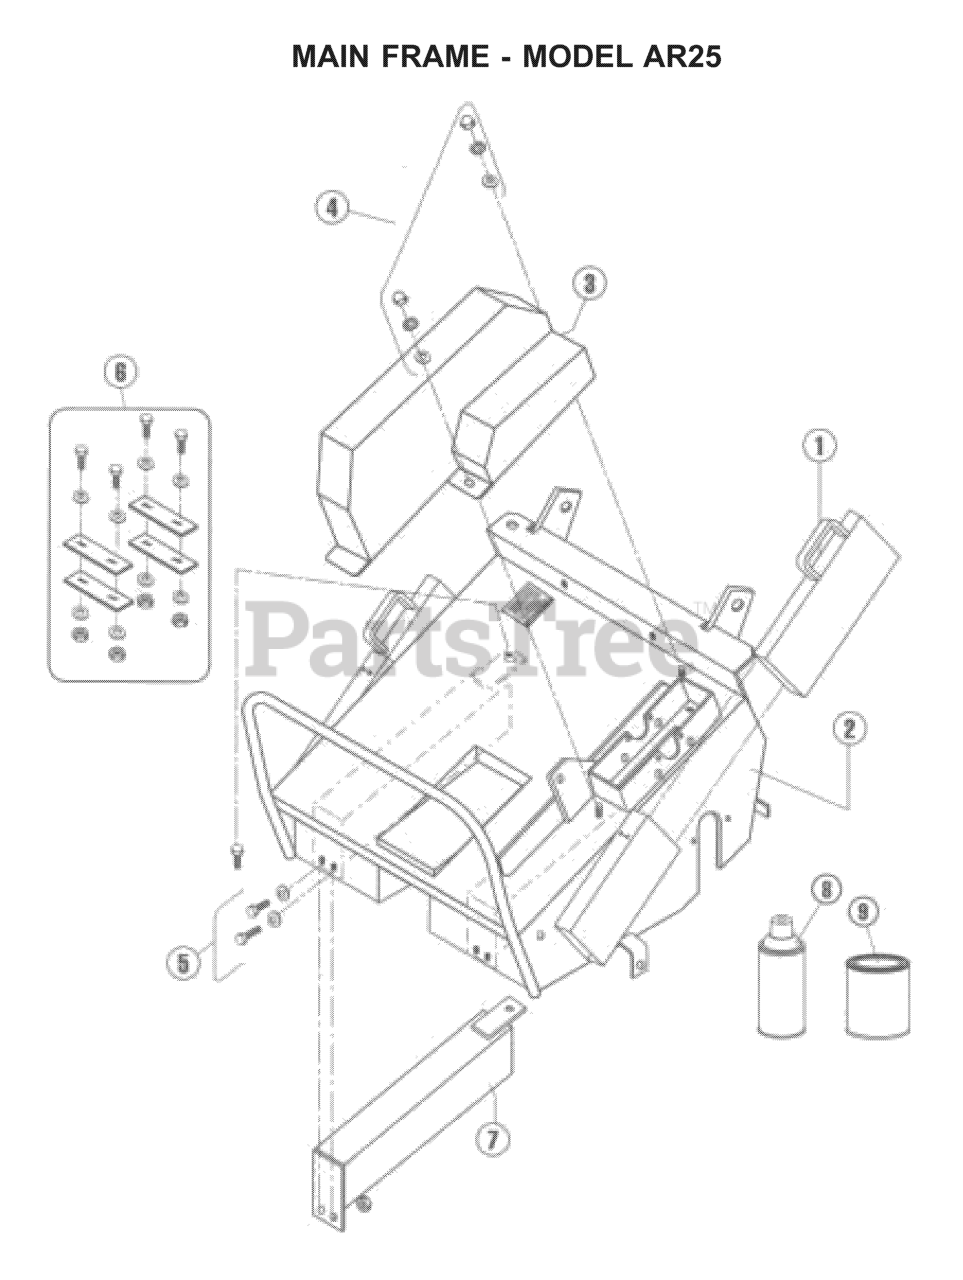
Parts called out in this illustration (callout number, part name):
1	WEIGHT, 36LBS
3	DRIVE GUARD
4	FASTENER KIT
5	FASTNER KIT
6	PLATE KIT FOR HONDA
7	36 IB WEIGHT, MOUNTED
8	PAINT 12.5 OZ SPRAY ORANGE
